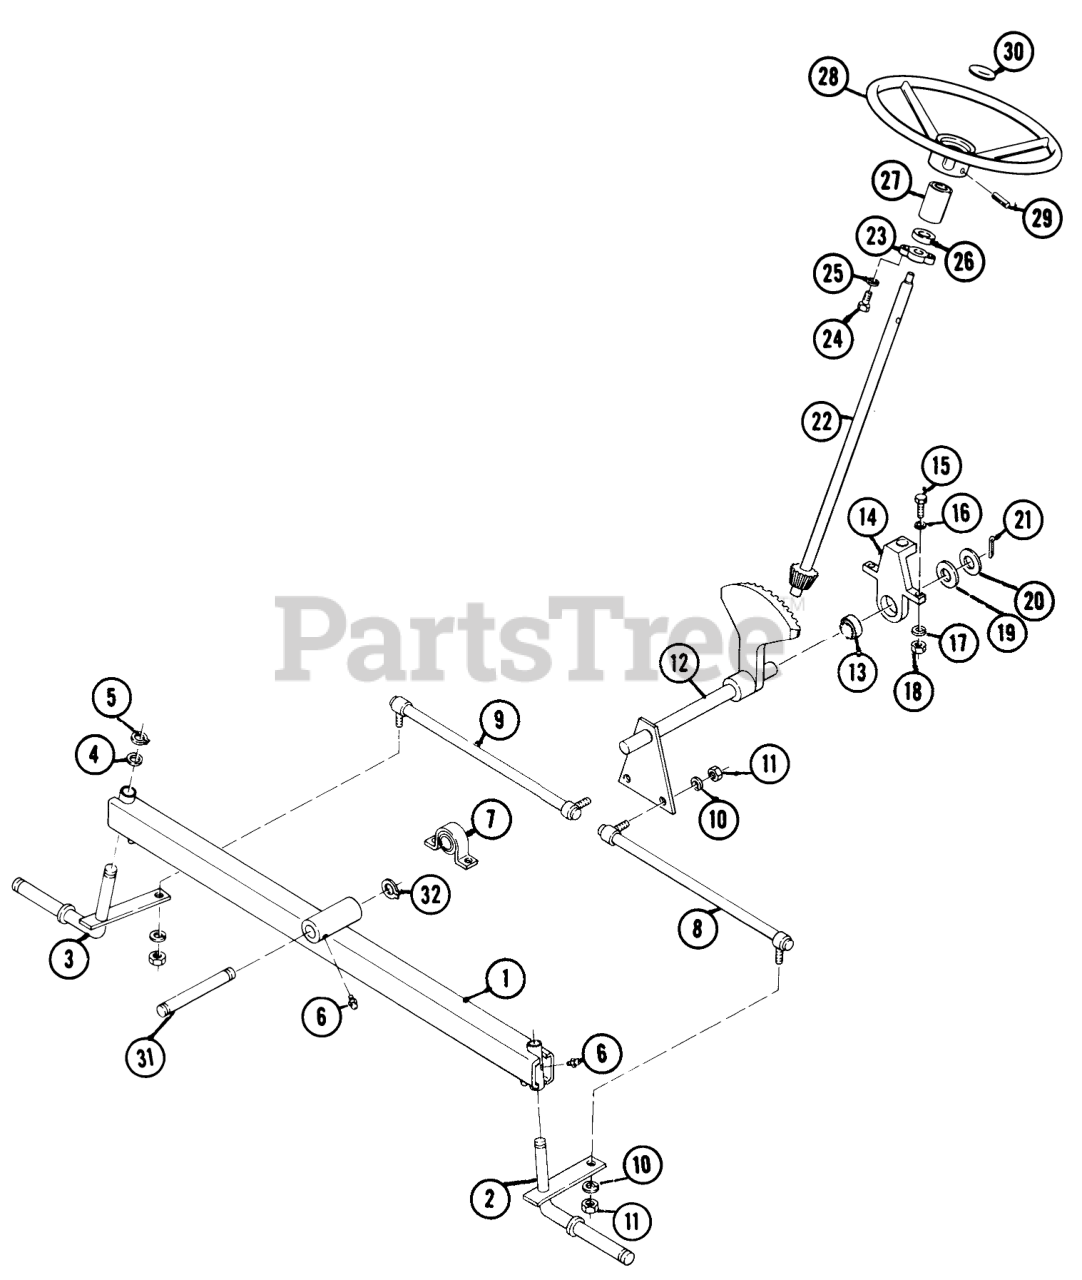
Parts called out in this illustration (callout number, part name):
5-01	Axle, Front
5-02	Spindle, Left
5-03	Spindle, Right
5-04	Thrust Washer
5-05	Snap Ring
5-06	Grease Fitting
5-07	BEARING
5-08	Tie Rod, Left
5-09	Tie Rod, Right
5-10	Lockwasher, 1/2
5-11	Nut, Hex Jam 1/2-20
5-12	Gear & Sector, with Shaft
5-13	Bearing
5-14	Mounting Bracket
5-15	Screw, Machine, Hex 5/16-18 x 2
5-16	Washer 5/16
5-17	Lockwasher-5/16
5-18	Nut, Hex 5/16-18
5-19	Shim Washer
5-20	Washer-3/4
5-21	Cotter Pin, 1/8 x 1 1/4
5-22	STRG SHAFT & PIN
5-23	Bearing, Upper Steering Shaft
5-24	Cap Screw, Hex 5/16-18 x 1/2
5-25	Lockwasher-5/16
5-26	Set Collar
5-27	Spacer, Steering Column
5-28	Steering Wheel
5-29	Spring Dowel Pin
5-30	STEERING WHEEL INSE
5-31	Pivot Pin
5-32	Retaining Ring
